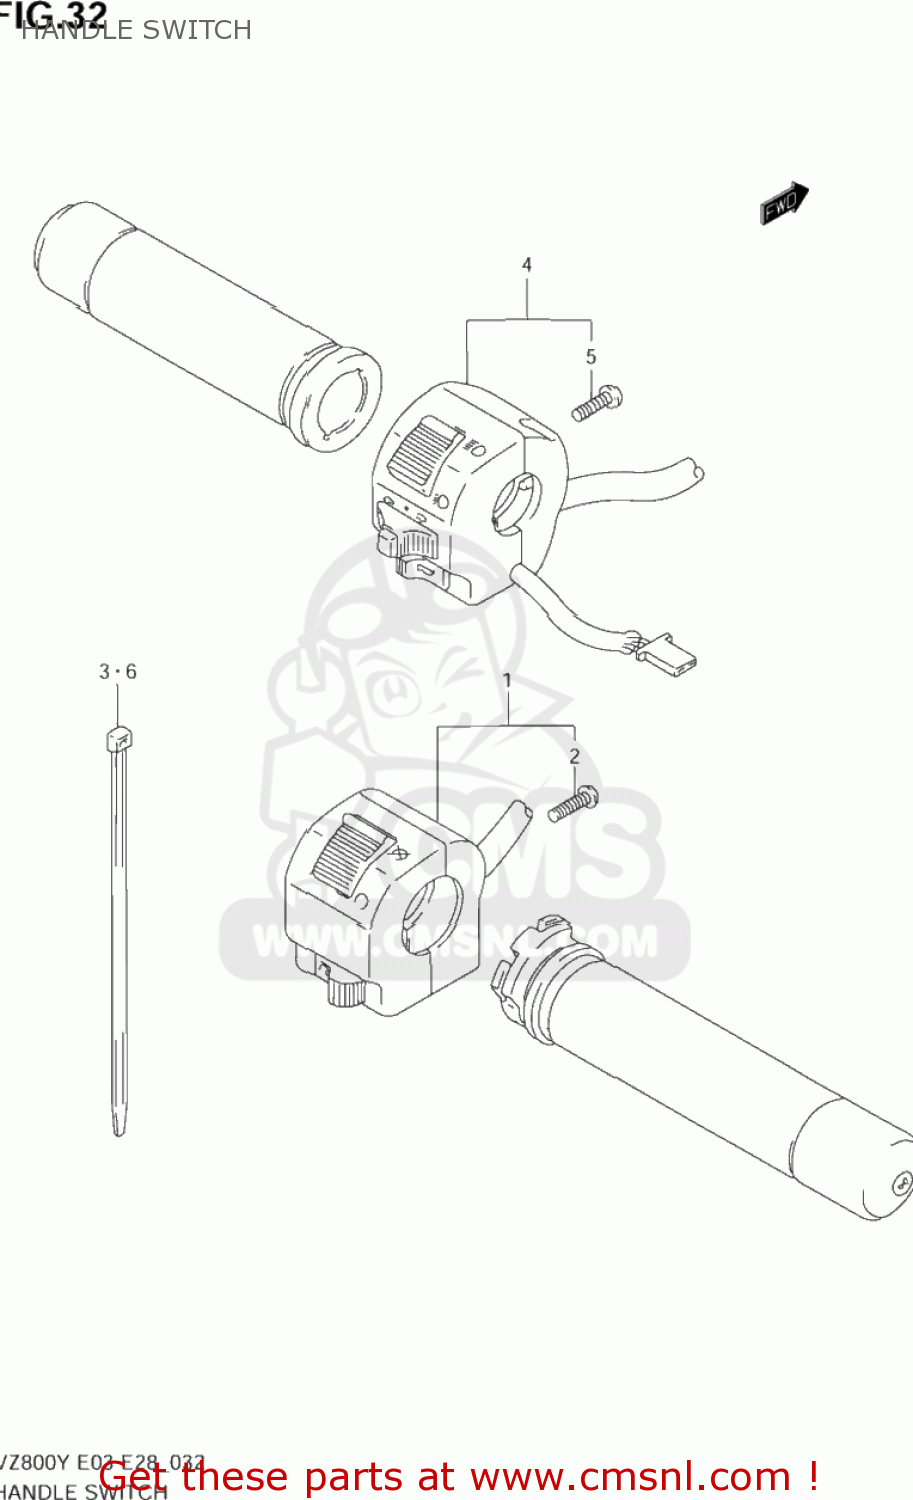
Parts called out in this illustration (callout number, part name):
1	SWITCH ASSY,HANDLE,R
2	SCREW(5X16)
3	CLAMP(L:145)
4	SWITCH ASSY,HANDLE,L
5	SCREW(5X16)
6	CLAMP(L:145)
